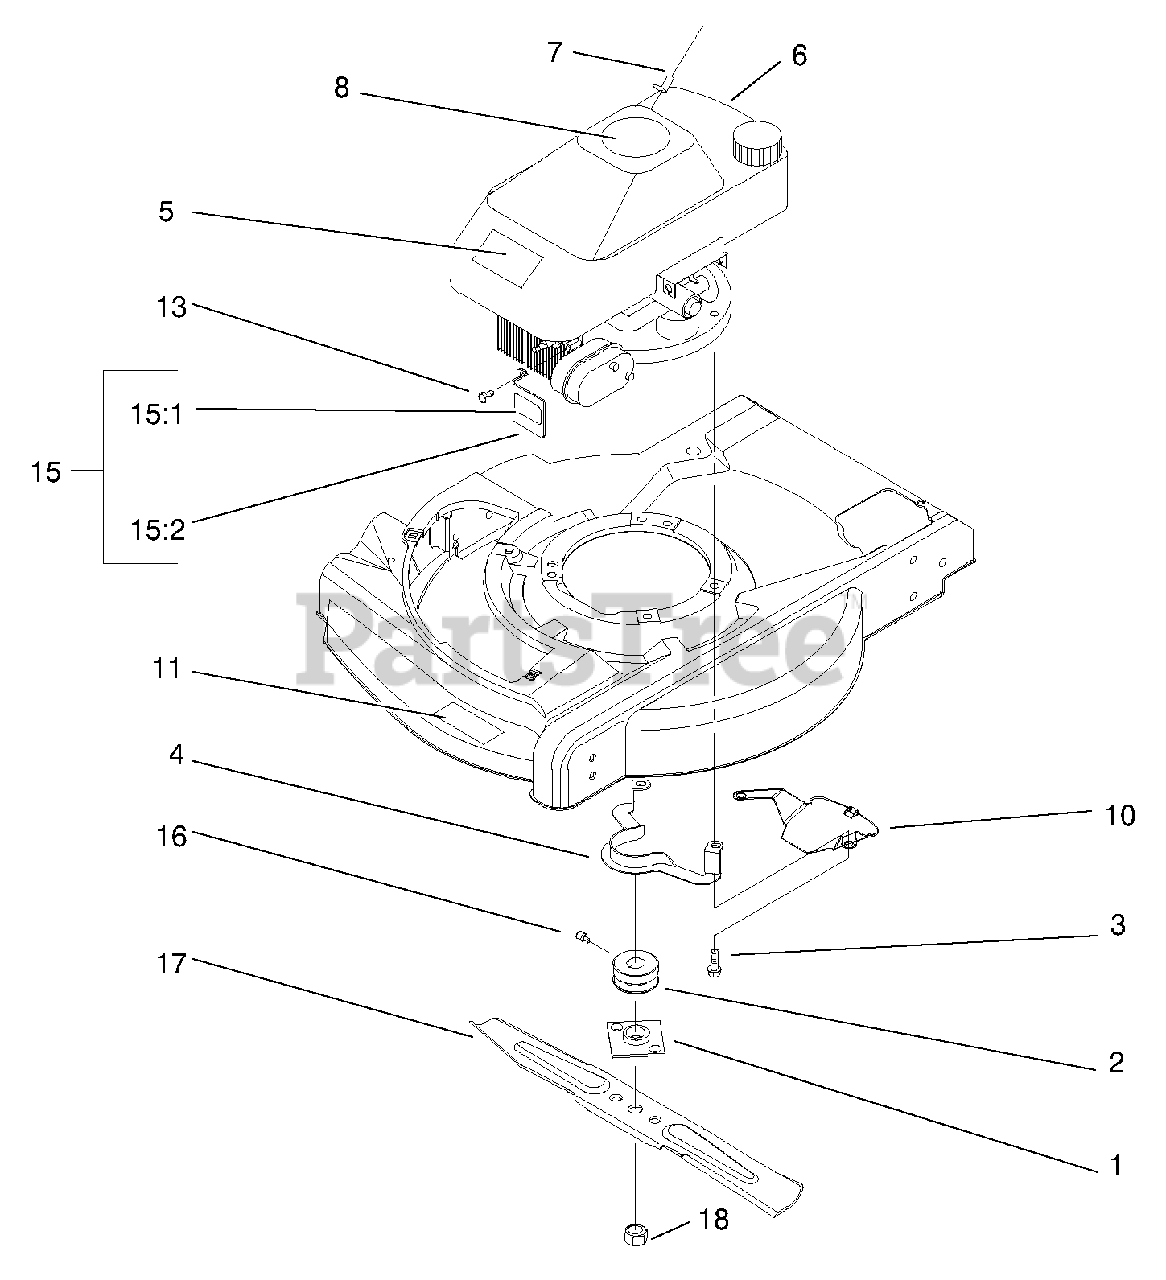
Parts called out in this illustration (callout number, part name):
1	Plate & Collar ASM
3	Screw-Taptite w/Patch
4	Guide-Belt
5	Applique
6	Engine-(Tecumseh
7	Rope-Stop
8	Decal-Recoil
10	Shield-Grass
11	Decal-Deck
15	Muffler Guard ASM
15:1	Decal-Surface, Hot
15:2	Guard-Muffler
16	Screw-Set,Cone Point
17	Blade
18	Nut-Blade
